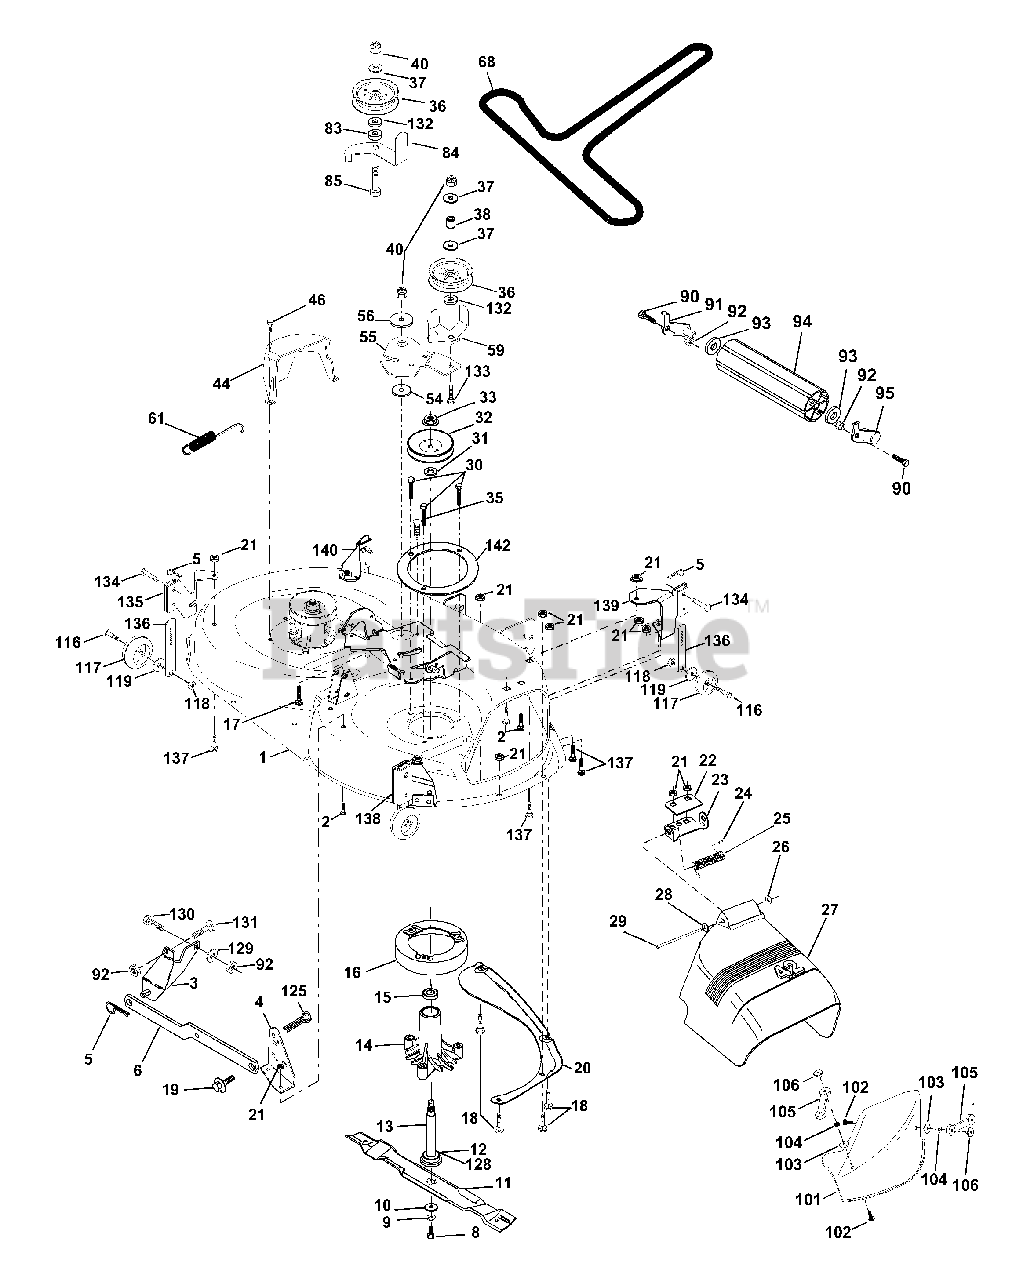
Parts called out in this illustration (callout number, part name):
1	Housing Asm Mower 42"
2	Bolt Rdhd Sqnk 5/16-18unc X 3/4
3	Bracket Asm Fr Sway Bar 38/42
4	Bracket Asm Deck 42" sway Bar
5	Retainer Spring
6	Arm Suspension Rear
8	Bolt 3/8-24x1 25 Gr8 Patched
9	Washer Lock Hvy 3/8 Unplated
10	Washer Hard Blade Mower Vented
11	Blade Mower Mulching 42"
12	Bearing Ball #6204 (Mandrel)
13	Shaft Asm W/lower Bearing
14	Housing Mandrel Vented (machd)
15	Bearing Ball Mandrel
16	Stripper Round Mower
17	Bolt Rdhd Sqnk 3/8-16 X 2-1/4
18	Bolt Carr 5/16-18 X 5/8
19	Bolt Shoulder
20	Baffle Vortex 42 Heavy Duty
21	Nut Crown Lock 5/16-18
22	Stiffener Bracket 42" deck
23	Bracket Deflector Mower 42"
24	Cap Sleeve 80 x 112 Blk Mower
25	Spring Torsion Deflector 2 52
26	Nut Push Phos & Oil
27	Shield Deflector Mower 42" Blk
28	Washer 11/32 X 5/8 X 16 Ga
29	Rod Hinge 42" 6 75 Wlg
30	Screw Thdrol Washer Head
31	Washer Spacer Mower Vented
32	Pulley Mandrel 42"
33	Nut 9/16 top Lock Flng Cntr
35	Fastner Christmas Tree
36	Pulley Idler Flat 3 060
37	Washer 13/32 X 13/16 X 16 Ga
38	Spacer Spring Stop Idler
40	Nut Lock 3/8-16 Unc
44	Guard Mandrel LH Black
46	Screw Thdrol 1/4-20x5/8
54	Washer Hardened
55	Arm Idler 42" mower LT/YT
56	Spacer Retainer Mower
59	Guard, Belt
61	Spring Ext. Elect
68	V-Belt Mower
83	Washer Sintered
84	Keeper Belt Idler
85	Bolt Carriage 3/8-16 x 2-1/2 Gr.5
90	Bolt Fin Hex 3/8-16unc X 1
91	Bracket Asm Noseroller LH
92	Nut Lock Hex w/ins. 3/8-16 UNC
93	Washer 17/32 X 7/8 X 16 Ga
94	Roller Nose 38 & 42
95	Bracket Asm Noseroller RH
101	Cover Mulching 42" Blk
102	Screw
103	Washer #10
104	Washer Lock #10
105	Latch Asm Bagger
106	Nut Weld .327/.304 #10-24
116	Bolt Shld
117	Wheel Gauge Donut
118	Nut Centerlock 3/8 - 16 UNC
119	Washer 3/8 x 7/8 x 14 Ga.
125	Cotter Pin
128	Washer Felt
129	Washer 13/32 x 13/16 x 12 Ga.
130	Bolt Fin Hex 3/8-16unc x 1 Gr. 5
131	Bolt Rdhd Sqnk 3/8-16 UNC
132	Washer 13/32 x 1-3/8 x 3 Ga.
133	Bolt Rd Hd 3/8-16 UNC x 2-3/4 Gr.5
134	Pin Head Rivet
135	Bracket Asm Whl Ga. Rear LH 42"
136	Bar Pnt Adjusting Wheel Gauge
137	Bolt Carriage 5/16-18 x 5/8 Short
138	Bracket Asm. Whl Ga. Rear RH 42"
139	Bracket Asm. Whl Ga. Front RH 42"
140	Bracket Asm. Whl Ga. Front LH 42"
142	Reinforcement Mandrel Ring
